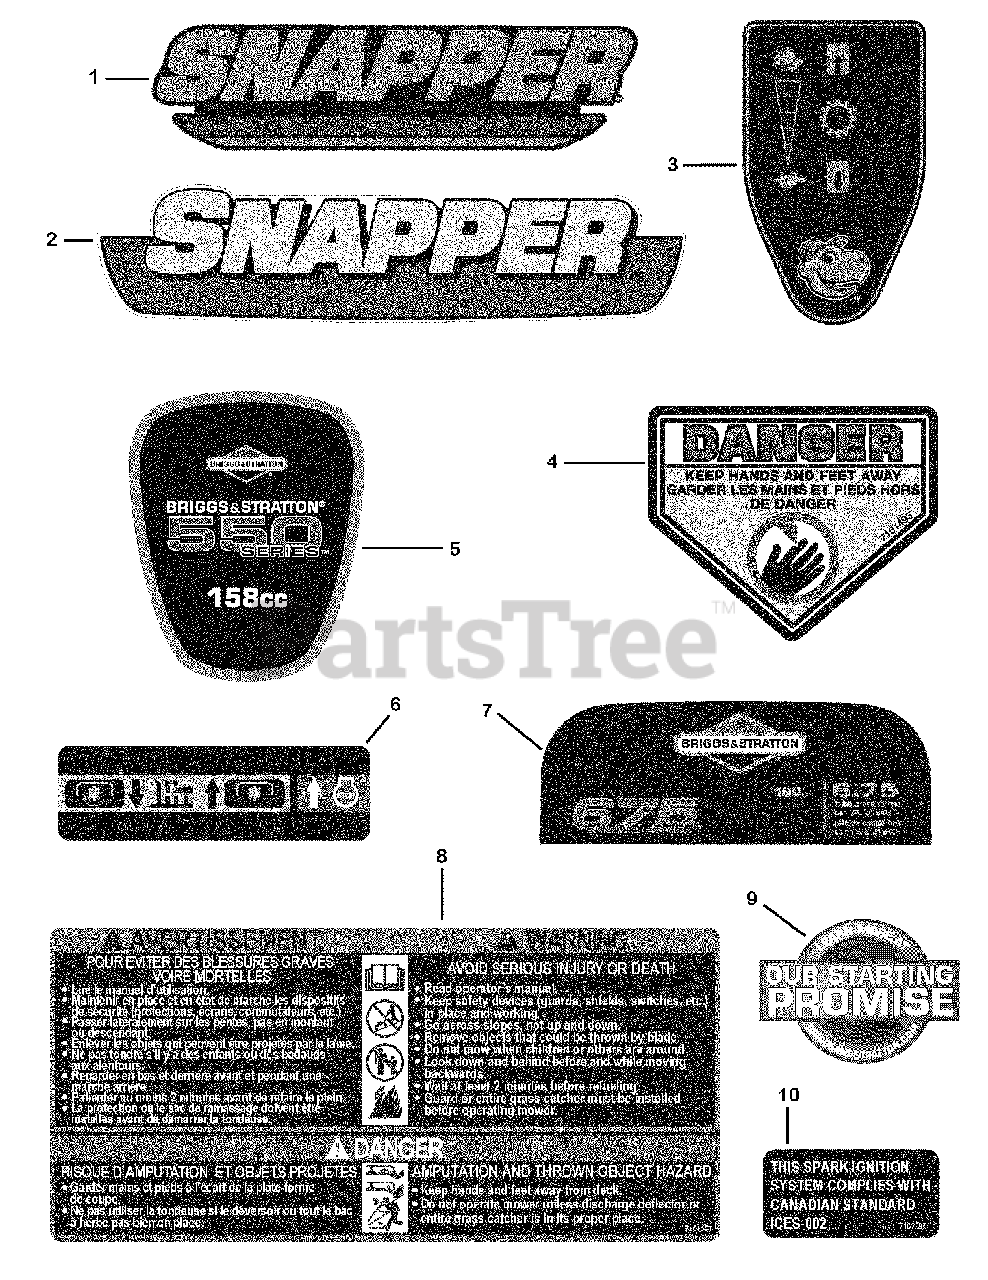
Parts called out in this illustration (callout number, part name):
1	DECAL, Front Shroud, Snapper Logo
2	DECAL, Briggs Engine, SNAPPER (Red)
3	DECAL, Snapper, Drive Cover
4	DECAL, CPSC, Danger, French / English
5	LABEL, Engine, 550TP
6	DECAL, Instruction, Engine Lever
7	DECAL, Engine, 675TP, SNAPPER
8	DECAL, French / English, Safety
9	LABEL, Starting Promise
10	DECAL, ICES, Canadian Spark Compliance
